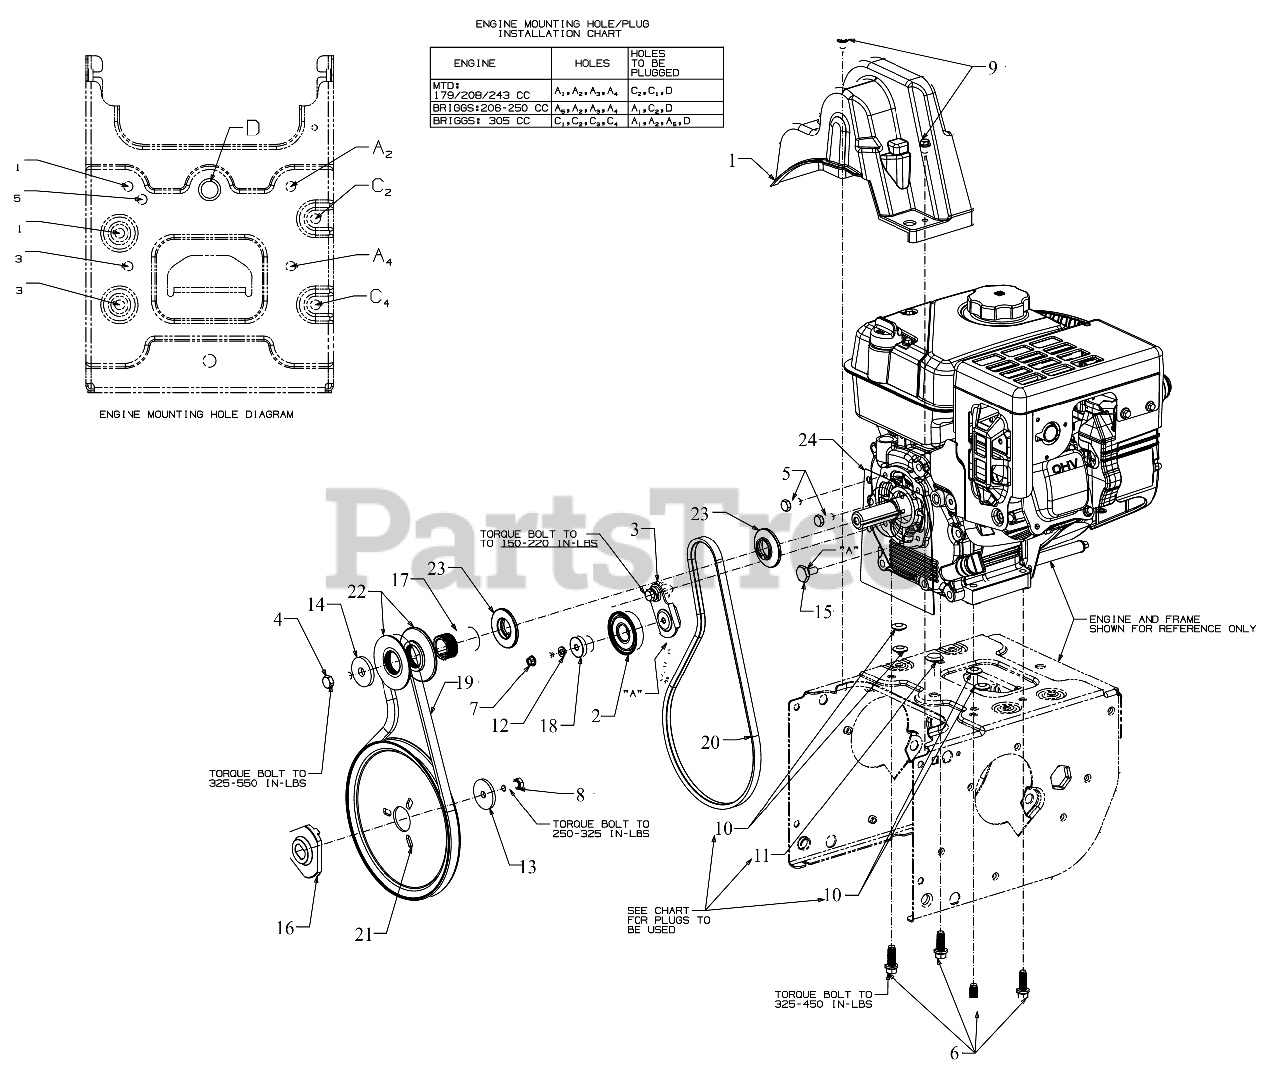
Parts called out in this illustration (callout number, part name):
1	BELT COVER (SMALL BLOCK)
2	IDLER PULLEY ASSEMBLY
3	ENGINE IDLER ASSEMBLY
3	SCREW 5/16-24 x 1.25 GR5
3	TORSION SPRING
3	LOCK WASHER 5/16
3	SHOULDER SPACER
3	IDLER BRACKET
3	PUSH ON NUT
3	IDLER BRACKET SPACER .340X.750X.330
4	SCREW 3/8-24X1.25
5	SCREW 5/16-24 x .750 GR5
6	SCREW 3/8-16 x 1
7	SCREW 1/4-20 x 1.25
8	SCREW 5/16-24 x .875 GR5
9	SCREW 1/4-20X.625
10	PLUG-3/8 DIA ID x 3/32
11	PLUG-1/2 ID x 3/32
12	LOCK WASHER
13	FLAT WASHER
14	FLAT WASHER .45 x 1.5 x .172 HT
15	SHOULDER SCREW
16	ADAPTER PULLEY .75 DIA W/DD
17	PULLEY SPACER
18	SHOULDER SPACER
19	V-BELT .500 x 35.
19	Cub Cadet AUGER BELT
19	Genuine Factory Parts AUGER BELT
20	V-BELT 3L x 34.18
20	Cub Cadet TRANSMISSION BELT
20	Genuine Factory Parts TRANSMISSION BELT
21	AUGER PULLEY
22	HALF PULLEY 4L V x 2.6 OD
23	HALF PULLEY-3/8 V x 1.7160
24	COVER PLATE
